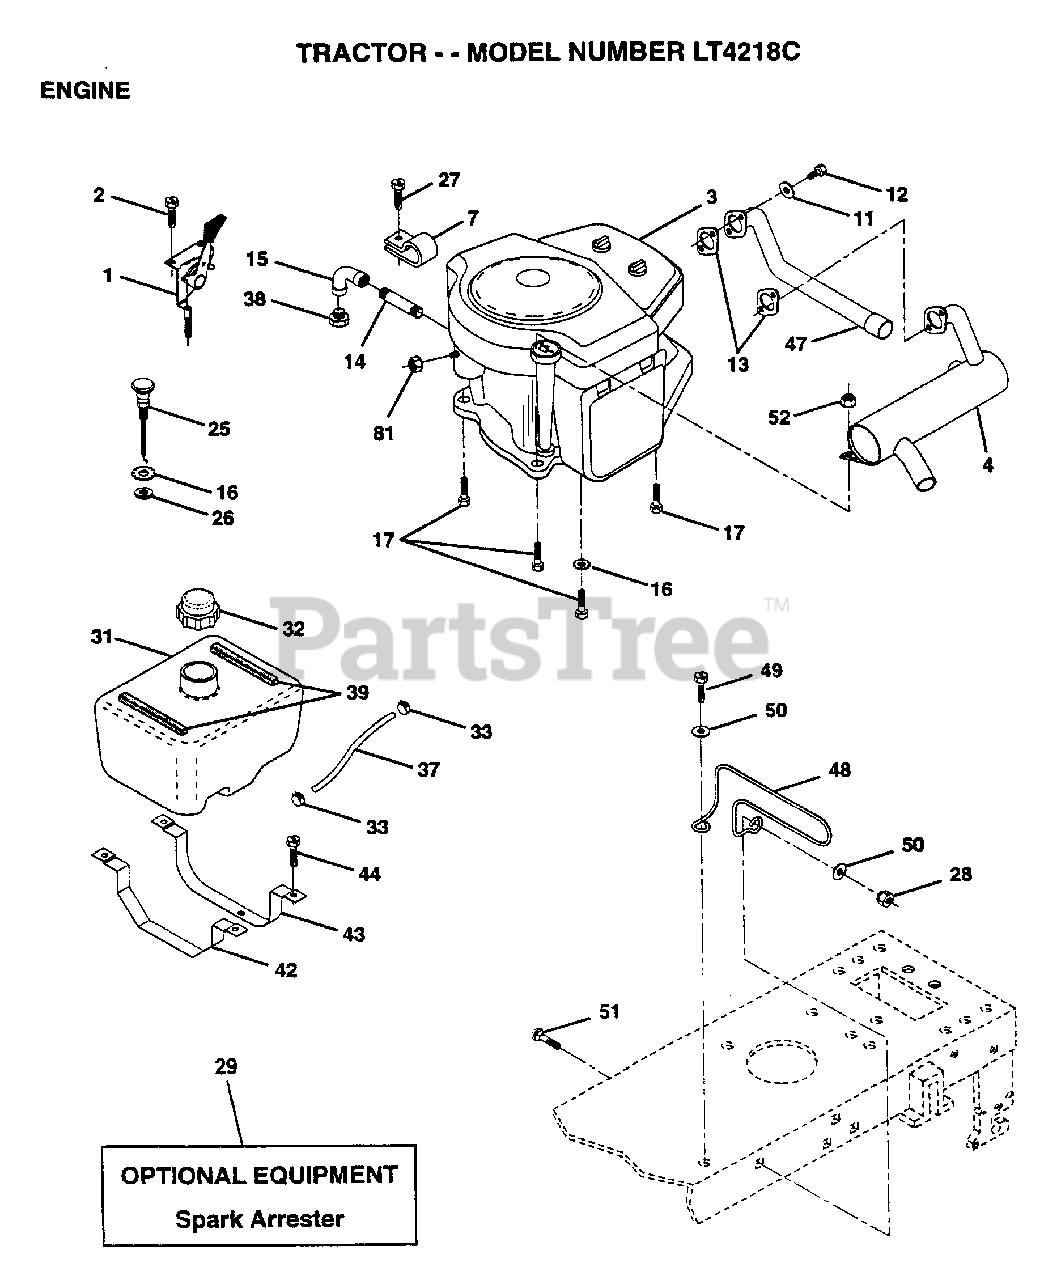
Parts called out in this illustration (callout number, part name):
1	CONTROL.THT.FLG.
2	SCREW LT
3	ENGINE B&S 18HP
7	CLAMP.TUBE.DBL.EN
11	LOCKWASHER
14	PIPE NIPPLE LT
15	ELBOW
16	LOCKWASHER
17	SCREW LT
25	"CONTROL.CHOKE.51"""
27	SCREW.10-24X1/2
31	TANK FUEL 1.9 NAT
32	CAP ASM FUEL
33	HOSE CLAMP
37	FUEL LINE T
39	"STRIP,FORM"
42	STRAP TANK FUEL
43	STRAP TANK FRONT
44	SCREW
47	EXHAUST TUBE T
48	MUFFLER GUARD
49	SCREW
50	WASHER HYT
51	BOLT D
52	NUT
81	NUT
